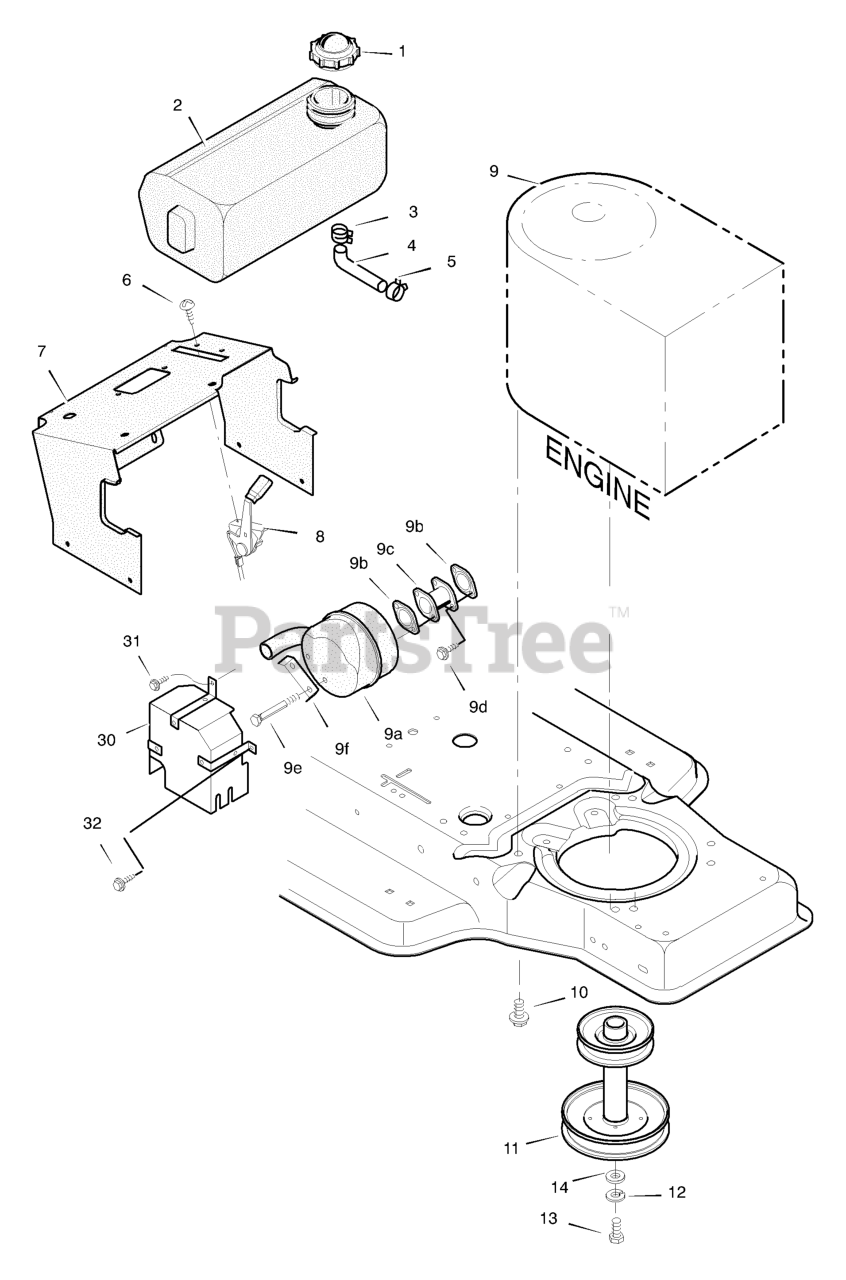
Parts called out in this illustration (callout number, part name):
1	Fuel Cap
2	Fuel Tank
3	Hose Clamp
4	Fuel Line (Must cut to length)
5	Hose Clamp
7	Support, Dash
8	Throttle Control
9	Engine
10	Bolt, Engine Mount
11	Stack Pulley Assembly
12	Lockwasher
13	Bolt, Hex
30	Shield, Heat
